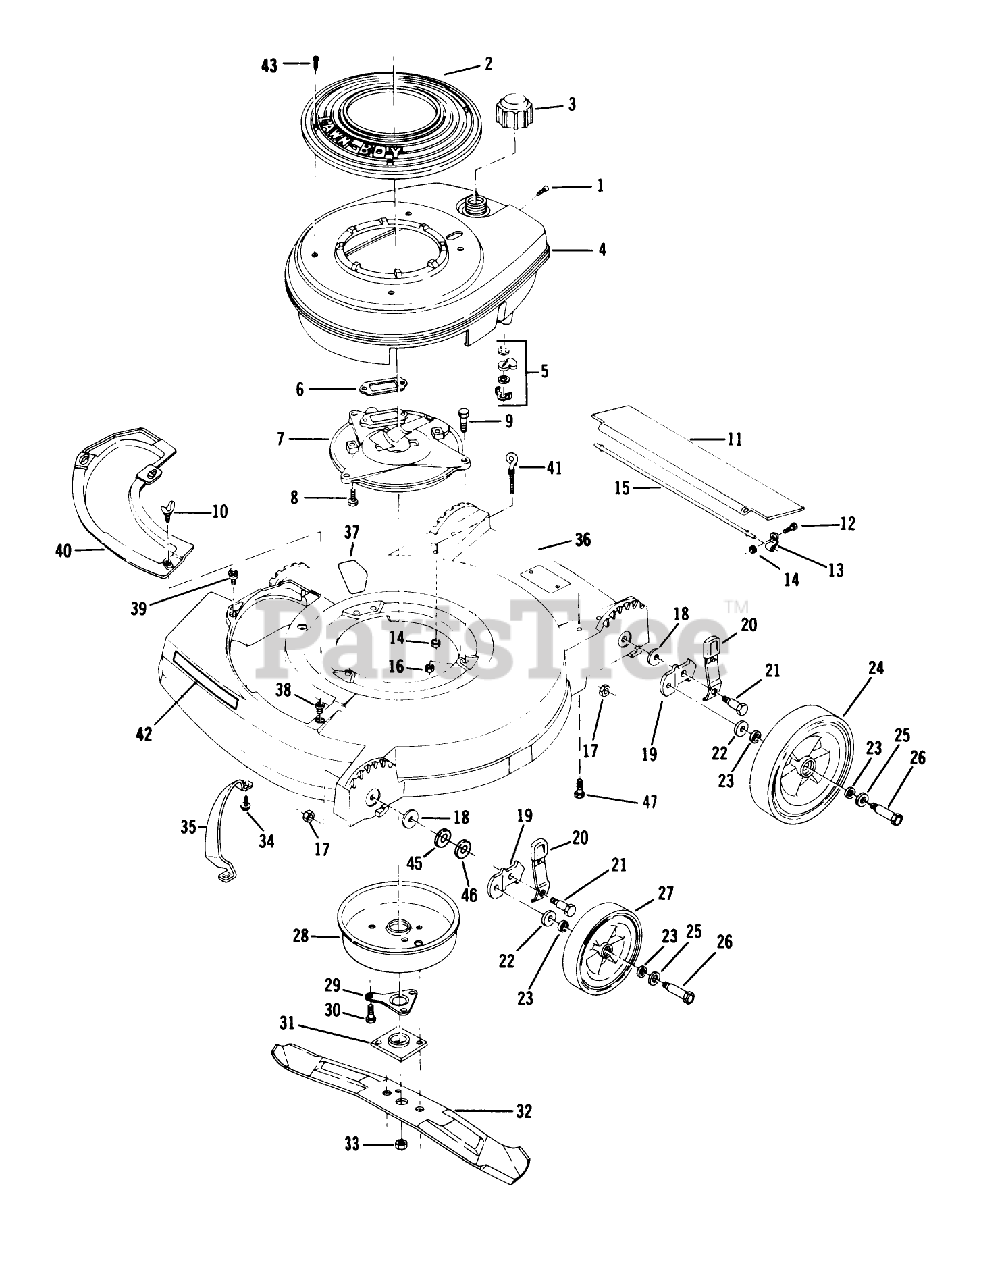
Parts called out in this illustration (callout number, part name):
1	SCREW S
3	FUEL CAP & INSERT
5	SHUT OFF VALVE KIT
7	PLATE F
8	SCREW V
9	SCREW-HH
10	WING SCREW LAWRE
13	CLAMP ROD KMC
14	LOCKNUT E
15	ROD 21" ADVANCE
16	NUT-LOCK F
17	LOCKNUT
18	WASHER
20	SPRING ARM ASM
21	BOLT
22	WASHER WROUGHT
23	WASHER
25	SPACER
26	BOLT WHEEL
27	WHEEL & TIRE KIT
28	MUFFLER COVER F
29	SUPPORT F
30	SCREW
31	PLATE AND COLLAR ASM
33	NUT-BLADE
35	BAR-TOE
41	BOLT-EYE
43	SCREW - SELF TAPPING
45	WASHER
46	WASHER
47	SCREW
